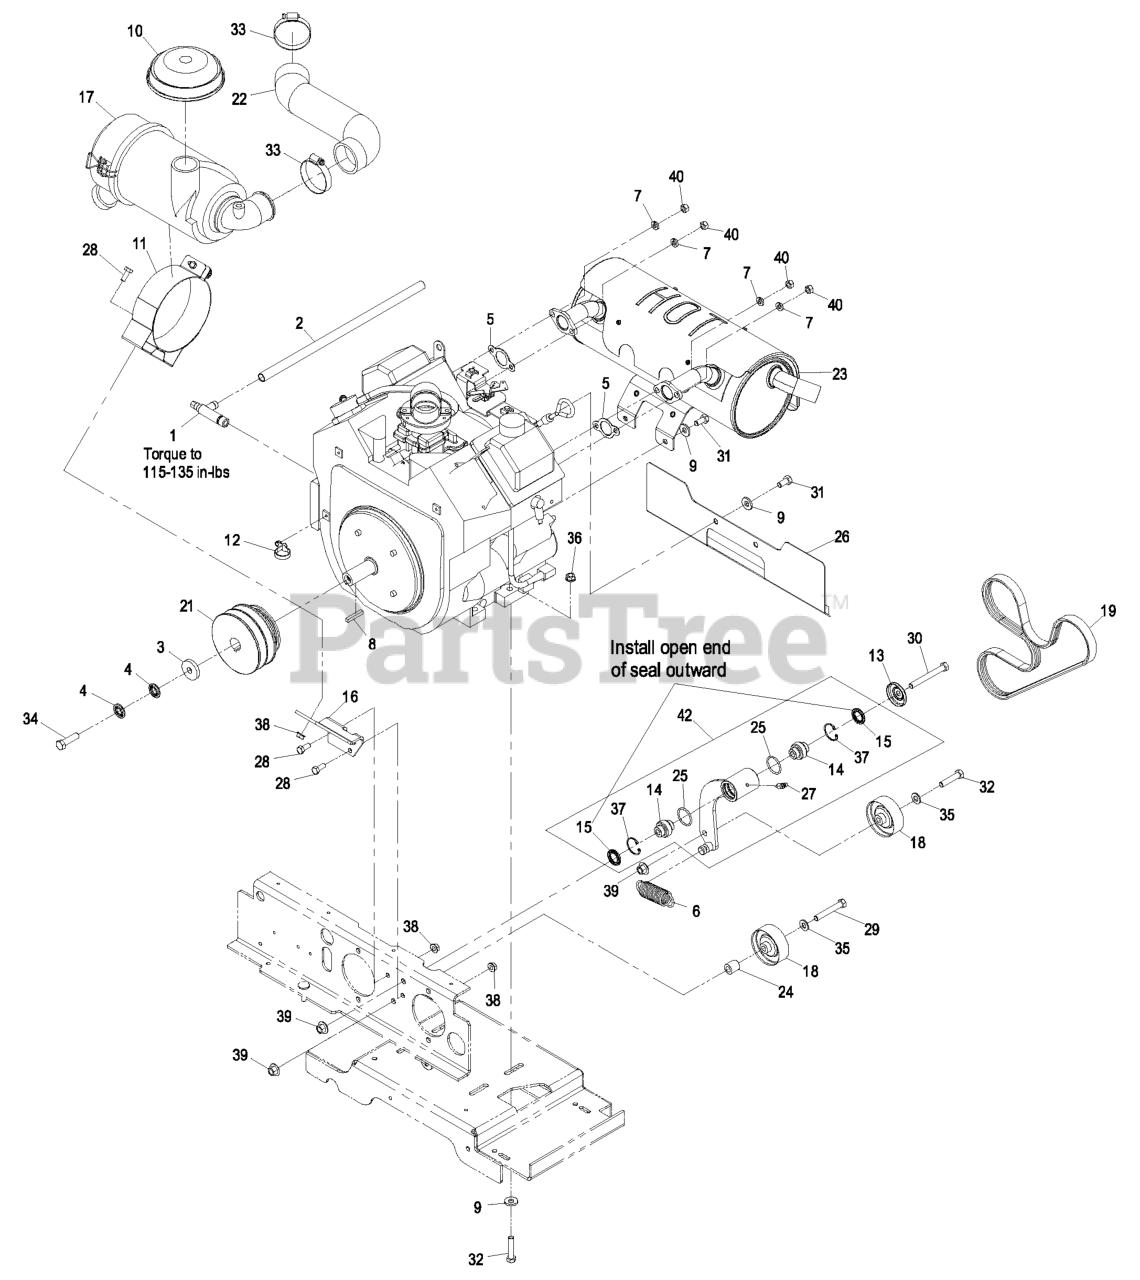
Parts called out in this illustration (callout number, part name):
1	VALVE-DRAIN, OIL
2	TUBE-DRAIN, OIL
3	WASHER-CLUTCH
4	WASHER-SPRING
6	SPRING-IDLER
7	WASHER-LOCK
8	KEY-SQUARE
9	WASHER-BELLEVILLE
10	HOOD-CLEANER, 2" AIR INTA
11	BRACKET-FILTER, AIR
12	Tie, Cable
13	GUARD-TOP
14	BEARING-SPHERICAL
15	SEAL-LIP, SINGLE
16	BRACKET-FILTER, AIR
17	AIR CLEANER CANISTER ASM
19	BELT-V
22	HOSE-AIR INTAKE
24	SPACER-MOUNTING, STEERING
26	SHIELD-EXHAUST
27	FITTING-LUBE, 45 DEG
28	SCREW-HH
29	BOLT-CARR
30	SCREW-HH
31	SCREW-HH
32	SCREW-HH
33	CLAMP-HOSE
34	SCREW-HH
35	WASHER-FLAT
36	NUT-HHF, WHIZ
37	RING-SNAP
39	NUT-FLANGE
40	NUT-HEX
42	IDLER ASM
